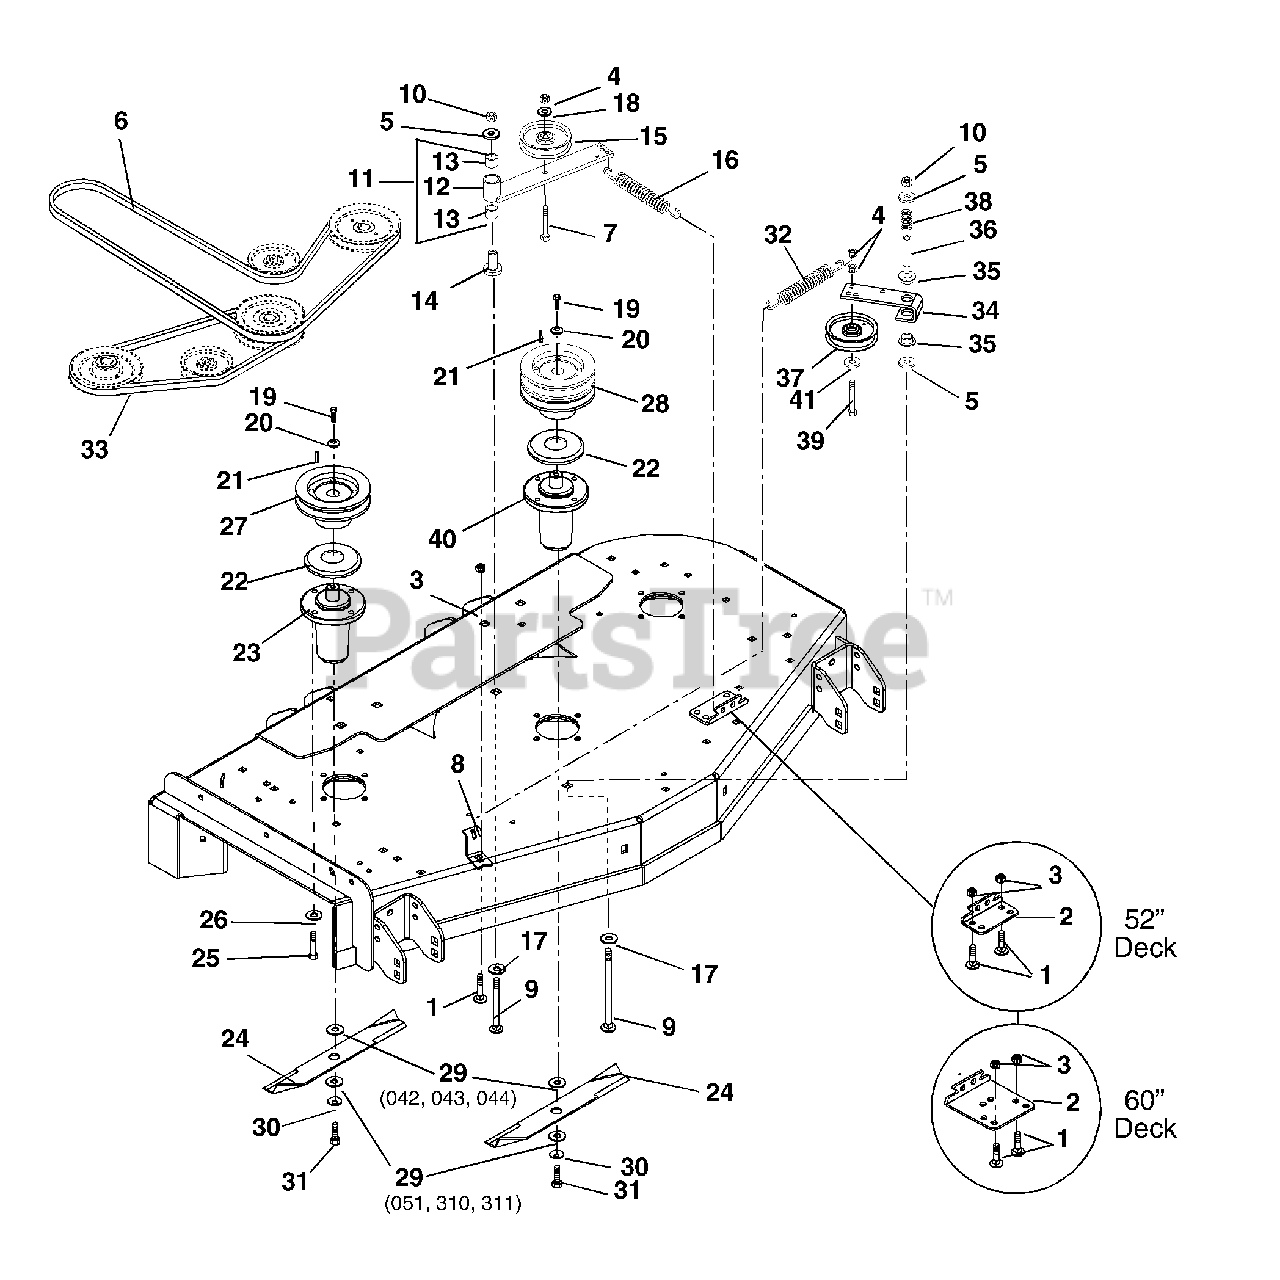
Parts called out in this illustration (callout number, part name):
1	@BLT-RDHDSQNK .38-16X.75 G5YZ
1	@BLT-RDHDSQNK .38-16X1.25 G2YZ
2	BRACKET, SPRING - ORANGE
2	BRACKET, SPRING
3	@NUT-LK-TOP-FLG .38-16 YWZC
4	@NUT-LK-CTR .38-16 YWZC
5	WSHR-FL-STL .531X1.250X.10 YWZ
6	V-BELT, HB-WRAPPED
6	V-BELT, B-WRAPPED
7	@BLT-HEX .38-16X2.75 GR5 YWZC
8	ANCHOR, SPRING - ORANGE
9	@BLT-RDHDSQNK .50-13X3.50 G5YZ
10	@NUT-LK-TOP-FLG .50-13 YWZC
11	ASSEMBLY, IDLER PIVOT ARM
12	WELDMENT, IDLER PIVOT ARM
13	BRG, 1.00 X 1.12 X .75
14	BEARING, PEDESTAL
15	IDLER-FLAT 4.00X.38 (2.00 W)
16	SG-EXT-.090X1.00X6.00
17	WSHR-FL-STL.755X1.375X.062YWZC
18	WSHR-FL-STL .375X1.125X.065YWZ
19	BLT-HEX .38-16X1.00 YZ GR8
20	WASHER, CUPPED SERRATED, .375
21	KEY-SQ .25X1.0X.25 SAE 8630
22	SLINGER, DUST
23	ASM,MAINT FREE SPINDLE
24	BLADE, MOWER (18.00")
24	BLADE, MOWER (20.50")
24	BLADE - MULCHING (18.00")
24	BLADE, TUNG MULCH MOWER 60"
25	@BLT-HEX .38-16X1.00 GR5 YWZC
26	@WSHR-LK .38X.094 REG YWZC
27	WELDMENT, SPINDLE SHEAVE 5.00
27	WELDMENT, SPINDLE SHEAVE 6.00
28	SHEAVE, DOUBLE (5.25")
28	SHEAVE, DOUBLE (6.25")
29	WSHR-FLT .640X1.75X.250 YWZC
30	WSHR-BLVL .669X1.535X.138
31	BLT-HEX .62-18X1.75 GR8 YWZC
32	SPRING, EXT
33	V-BELT, 5L-RAW EDGE
33	V-BELT, HB-COGGED
33	V-BELT, HB-RAW EDGE
34	ARM,IDLER PIVOT
35	BSHG-FLG .762X1.0X.580X1.48 NY
36	SPACER .560X.750X2.437 ST
37	V-IDLER, 4.00X.38
38	SG-COMP .085X.80X1.00 WLD36
39	@BLT-HEX .38-16X2.25 GR5 YWZC
40	ASM,MAINT FREE SPINDLE
41	@WSHR-FL-STL.406X.812X.065 YWZ
